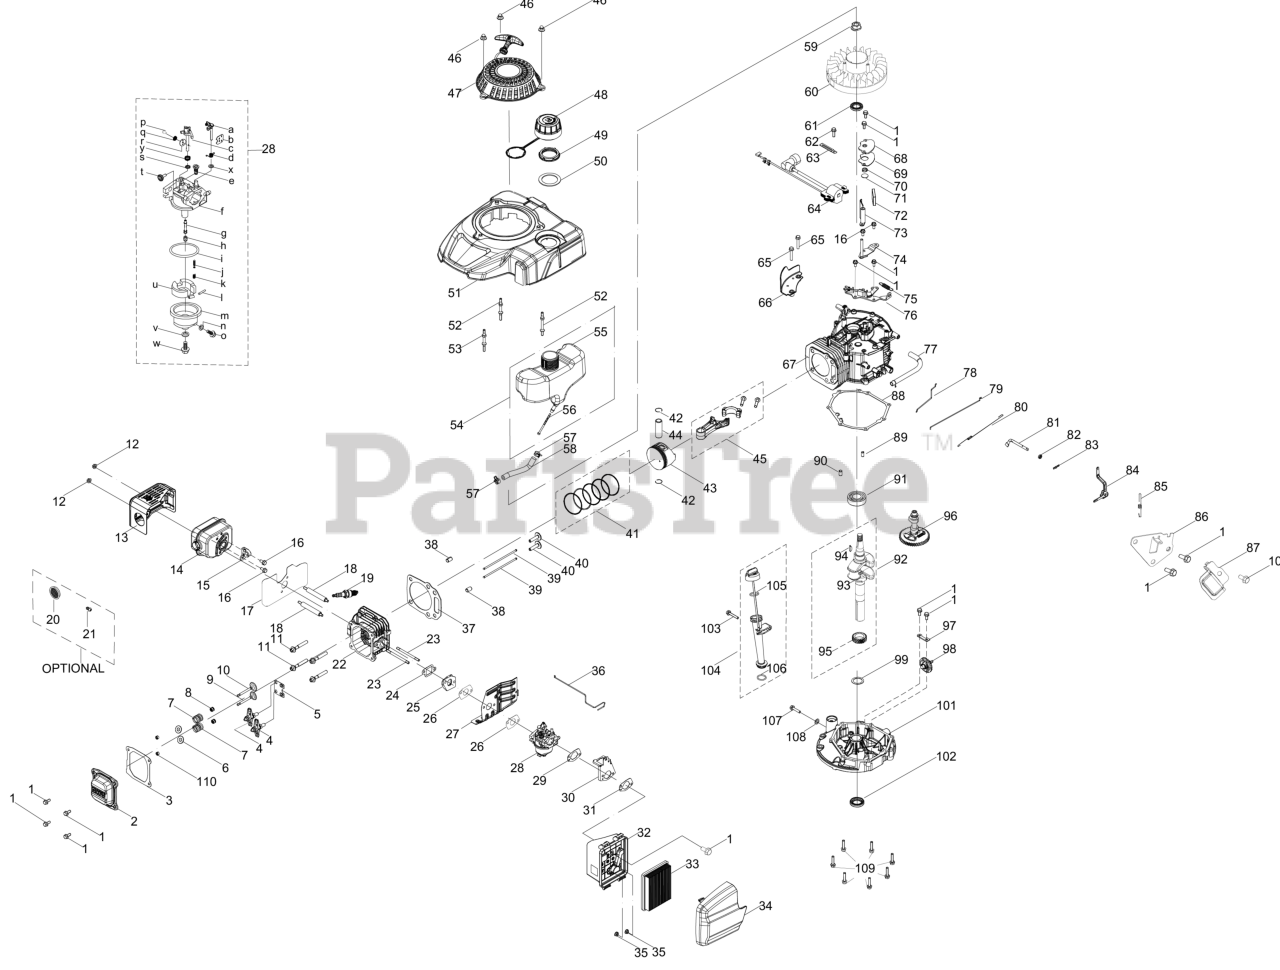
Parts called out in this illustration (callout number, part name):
1	BOLT M6-1 x 14 GR8.8
2	VALVE COVER
3	VALVE COVER GASKET
4	ROCKER ARM ASSEMBLY
5	CARBURETOR KIT (MAJOR)
6	VALVE SPRING SEAT
7	Valve Spring
8	INTAKE VALVE SEAL
9	Exhaust Valve
10	Intake Vavle
11	SCREW M8 x 54 GR10
13	MUFFLER SHIELD
14	MUFFLER ASSEMBLY
15	CHOKE TEMP CONTROL THERMOSTAT
16	BOLT M6-1 x 12 GR8.8
17	MUFFLER GASKET
18	STUD M6-1 x 95
19	SPARK PLUG
20	SPARK ARRESTOR
21	SCREW M3.5 x 9.5
22	Cylinder Head
23	STUD M6 x 90
24	MUFFLER GASKET
25	CARBURETOR INSULATOR
26	CARBURETOR GASKET
27	HEAT SHIELD
28	Carburetor
29	AIR FILTER BRACKET GASKET
30	AIR FILTER BRACKET
31	AIR FILTER BASE GASKET
32	AIR FILTER HOUSING BASE
33	AIR FILTER
34	AIR FILTER COVER
36	Choke Lever
37	CYLINDER HEAD GASKET
40	TAPPET
41	Piston Ring Set
42	PISTON PIN SNAP RING
45	CONNECTING ROD ASSEMBLY
46	ACORN NUT M6-1
47	RECOIL STARTER ASSEMBLY
48	FUEL CAP W/TETHER
49	FUEL TANK NUT
50	FUEL TANK UPPER GROMMET
51	ACORN NUT M6-1
52	STARTER/SHROUD REAR STUD
53	STARTER/SHROUD FRONT STUD
54	Fuel Tank Assembly
56	FUEL FILTER
57	CARBURETOR HOSE CLAMP
58	FUEL HOSE
59	FLYWHEEL NUT
61	CRANKSHAFT SEAL
62	SCREW M6-1 x 20 CL5.8
63	FLEXIBLE CLAMP
64	Ignition Module
65	BOLT M6-1 x 25 GR8.8
66	ENGINE BRAKE COVER PLATE
67	Crankcase
68	BREATHER COVER PLATE
69	BREATHER GASKET
70	BREATHER VALVE SPRING
71	BREATHER VALVE
72	BREATHER SCREEN
74	AIR VANE BRACKET
75	ENGINE BRAKE SPRING
76	ENGINE BRAKE ASSEMBLY
77	BREATHER HOSE ASSEMBLY
78	CHOKE LINKAGE
79	THROTTLE LINKAGE
80	THROTTLE SPRING
81	GOVERNOR ARM SHAFT
82	GOVERNOR SEAL
83	COTTER PIN
84	GOVERNOR ARM ASSEMBLY
85	GOVERNOR SPRING
86	COMPONENT BRACKET
87	GOVERNOR SHIELD
88	CRANKCASE COVER GASKET
89	DOWEL PIN
90	DOWEL PIN 9 X 14
92	CRANKSHAFT ASSEMBLY
93	Crankshaft
94	WOODRUFF KEY
95	TIMING GEAR
96	Camshaft
97	GOVERNOR GEAR MOUNTING PLATE
98	GOVERNOR GEAR
99	THRUST WASHER
100	BOLT M6-1 x 10 GR8.8
101	CRANKCASE COVER
102	LOWER CRANKSHAFT OIL SEAL
103	BOLT M6-1 x 35 GR8.8
104	Dipstick
107	OIL DRAIN PLUG
108	FLAT WASHER
109	BOLT-M6-1 x 28 GR8.8
S	Gasket
